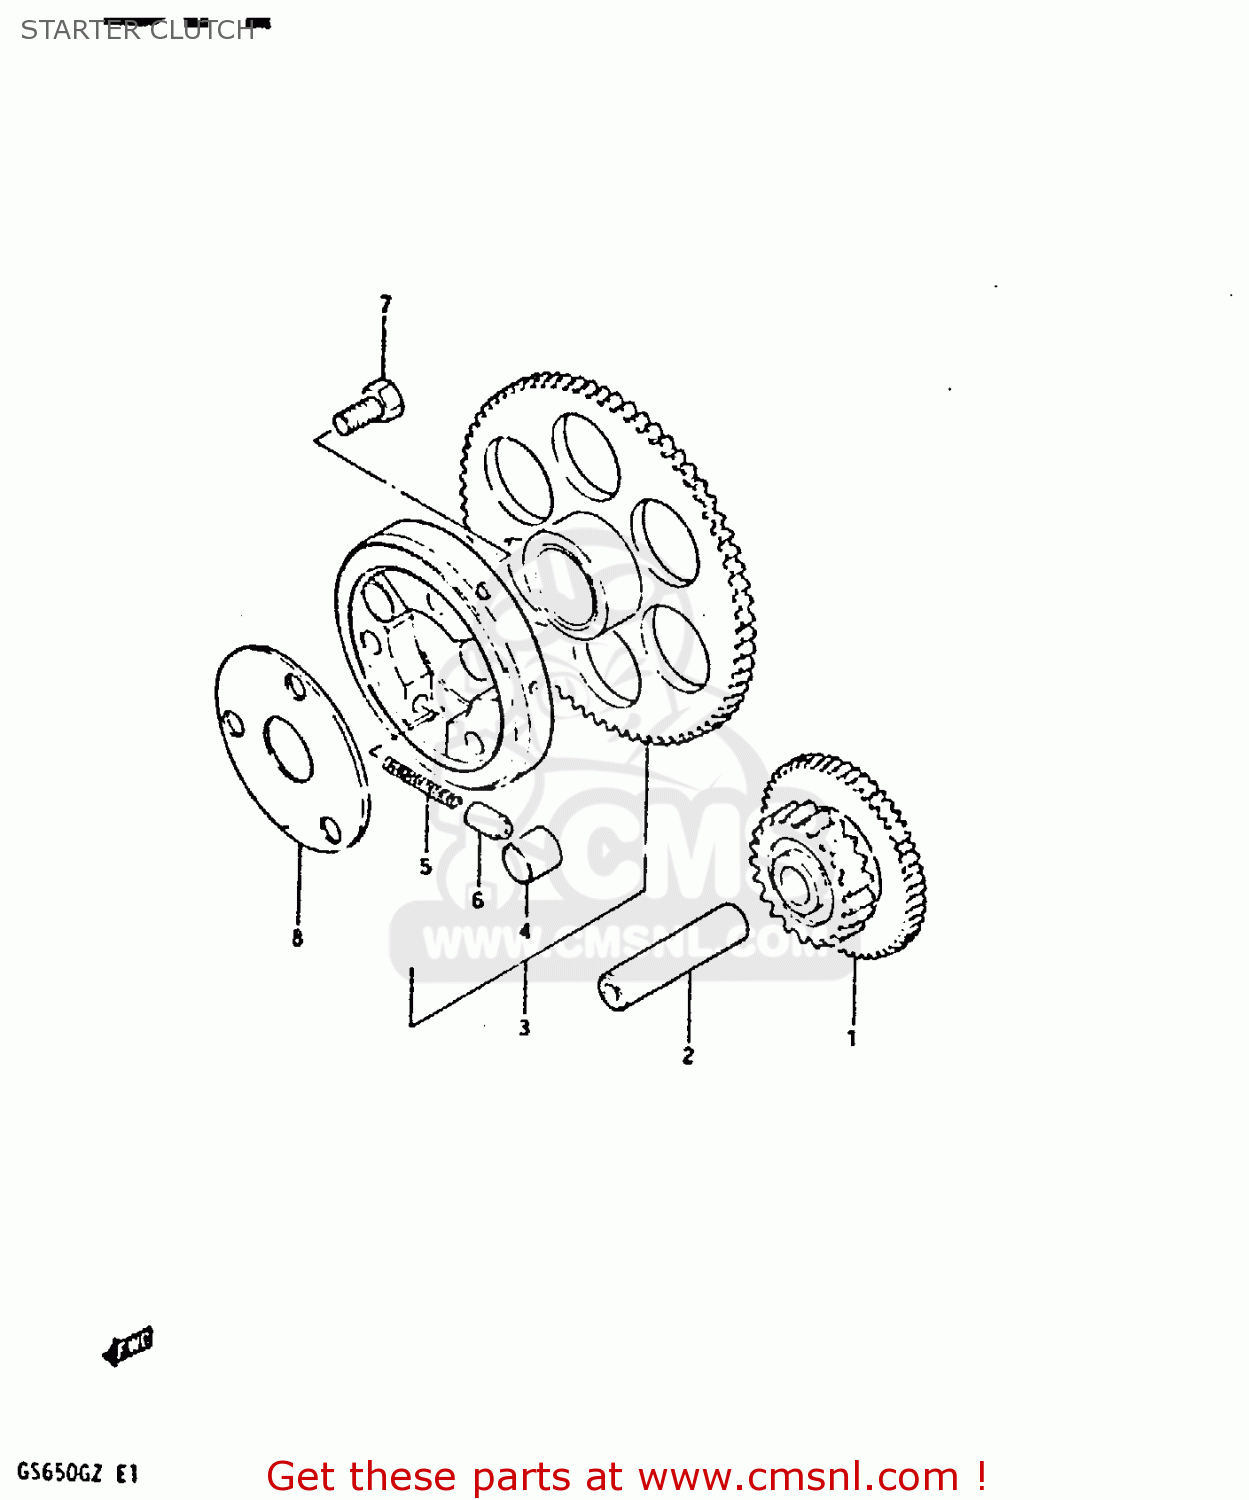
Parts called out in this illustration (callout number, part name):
1	GEAR,STARTER IDLE
2	PIN(7.4X13X56)
3	CLUTCH SET,STARTER
4	ROLLER(15X13)
5	SPRING
6	PIECE,PUSH
7	BOLT
8	SHIM, STARTER CLUTCH
